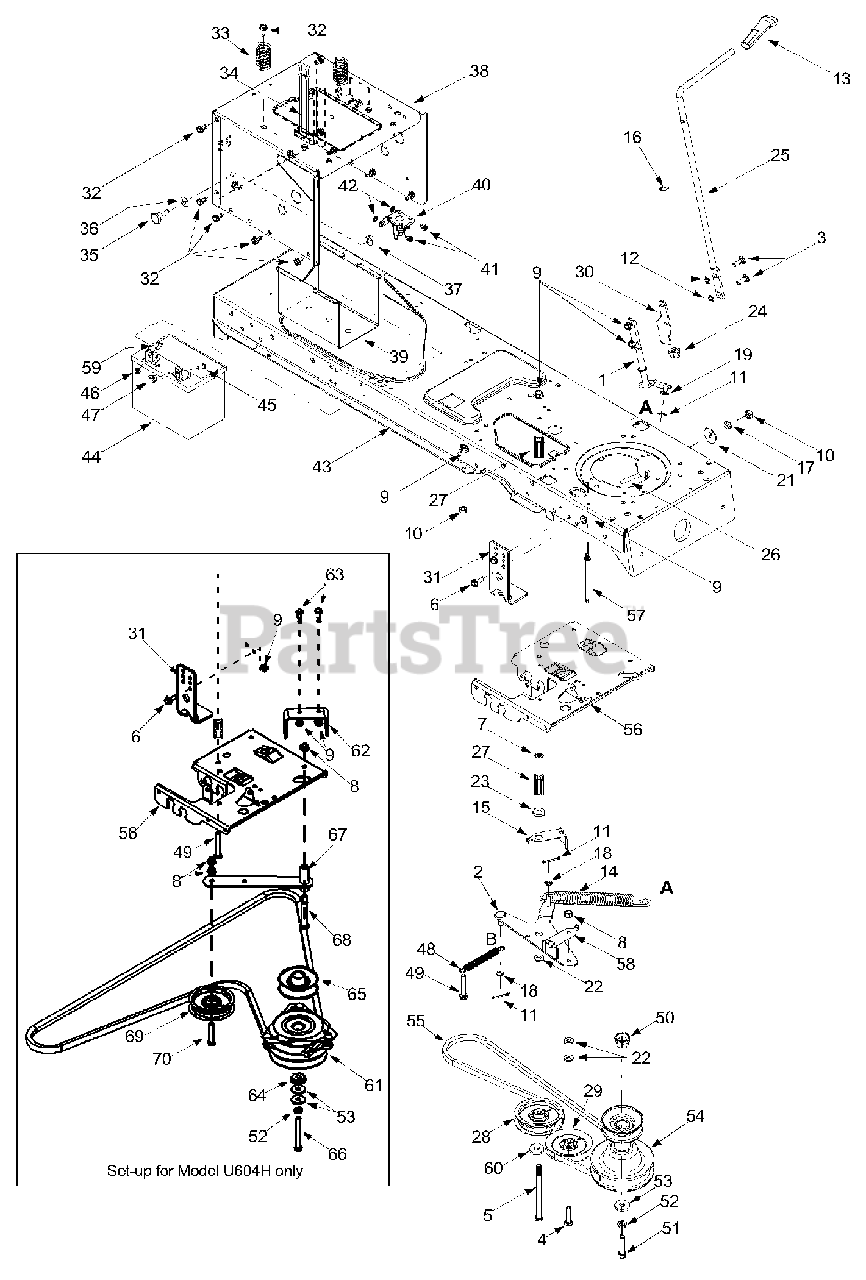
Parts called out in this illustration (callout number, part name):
1	PTO Engage Lever Assembly
4	Hex Cap Screw, 3/8-16 x 1.5
5	Hex Cap Screw, 3/8-16 x 5.5
6	Hex Head Washer Screw, 5/16-18 x .875
7	Push Nut, 3/8
8	Flange Lock Nut, 3/8-16
9	Flange Lock Nut, 5/16-18
10	Hex Nut, 5/16-18
11	Cotter Pin, 1/8 x 1.25
12	Speed Nut, .3125
13	PTO Knob
14	Extension Spring, .75 x 6.75
15	Belt Guard
16	Flat Washer, .510 x .750 x .033
17	Lock Washer, 5/16
18	Flat Washer, .385 x .62 x .063
19	Flat Washer, 5/16
21	Bell Washer, .39 x 1.13 x .062
22	Flat Washer, .407 x .812 x .135
23	Shoulder Spacer, .380
24	Hex Split Flange Bearing, .5
26	Belt Keeper Rod
27	Spacer, 3/8 x 1.54
28	Idler Pulley, 3.5
29	Idler Pulley, 4.0
32	Self-tapping Screw, 5/16-18 x .625
33	Compression Spring, 1.28 x 3.5
34	Battery Strap
35	Shoulder Screw, .625 x .5, 7/16-20
36	Bell Washer, .45 x 1.0 x .062
37	Flange Lock Nut, 7/16-20
41	Self-tapping Screw, 1/4-20 x .5
42	Lock Washer, 1/4
45	Shoulder Screw 1/4-20
46	Hex Sems Nut, 1/4-20
47	Wing Nut, 1/4-20
48	Extension Spring, .50 x 5.0
49	Hex Cap Screw, 5/16-18 x 1.75
50	Spacer Cup
51	Hex Head Cap Screw, 7/16-20 x 1.25
52	Lock Washer, 7/16
53	Flat Washer, .450 x 1.25
54	Engine Pulley, 3.56 OD x 5.56
55	PTO Belt
57	Keeper Pin, 5/16 x 4.75
58	Belt Guard
59	Screw 1/4-20 x 0.75
60	Flat Washer
61	Electric Clutch PTO
64	Shoulder Spacer
65	Engine Pulley
66	Hex Screw 7/16-20 X 3.25
69	Idler Pulley
70	Hex Screw 3/8-16 x 2.0
